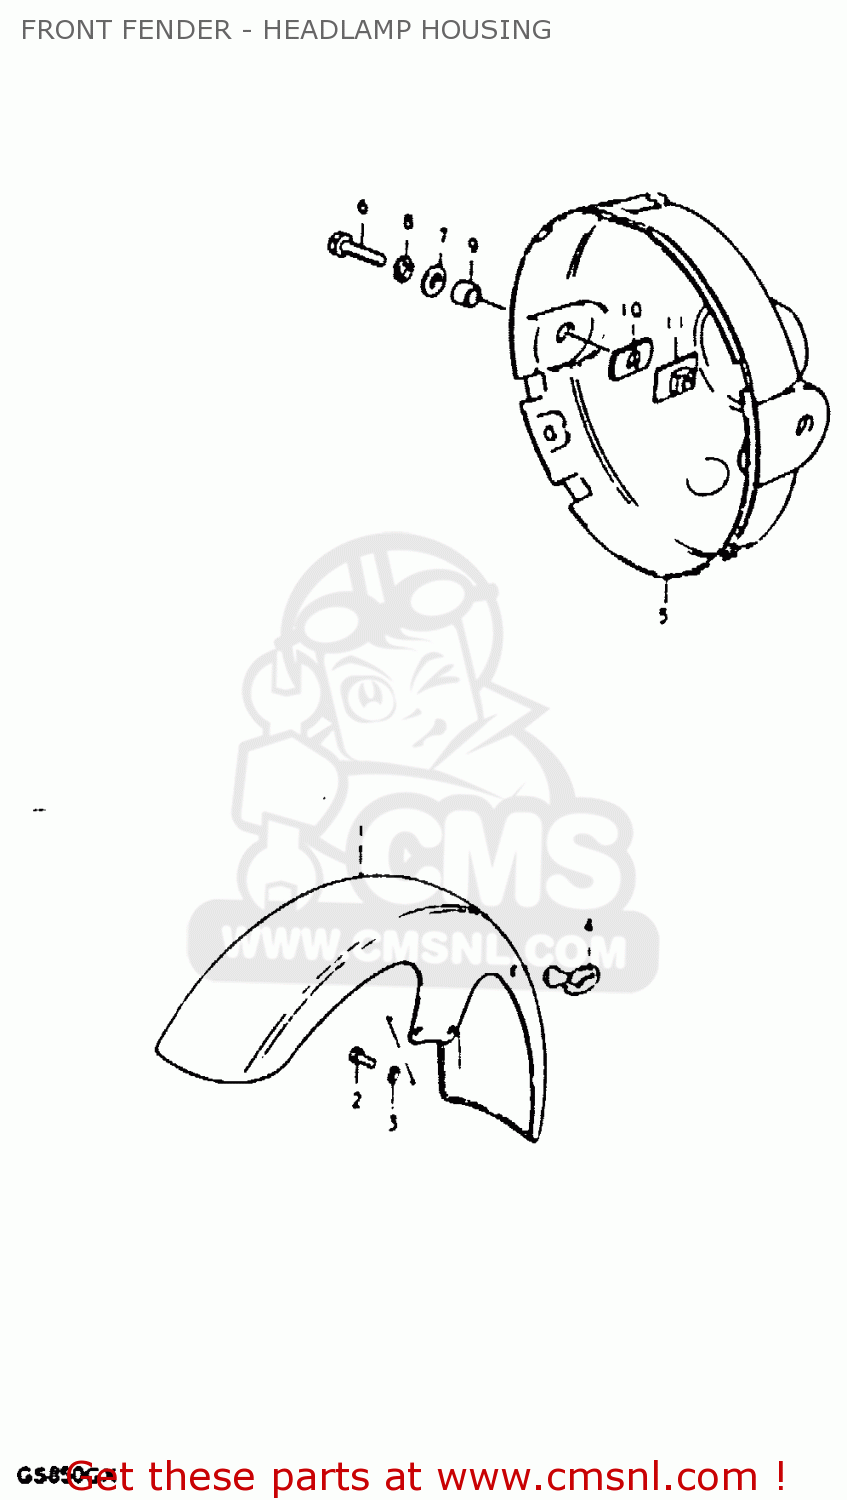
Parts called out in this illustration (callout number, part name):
1	FENDER,FR
2	BOLT
3	LOCK WASHER
4	GUIDE,CABLE
5	HOUSING,HEADLAMP(BLACK)
6	BOLT
7	WASHER 6MM
8	LOCK WASHER
9	SPACER (8.8X12X7)
10	CUSHION
11	PLATE,HEADLAMP HOUSING
